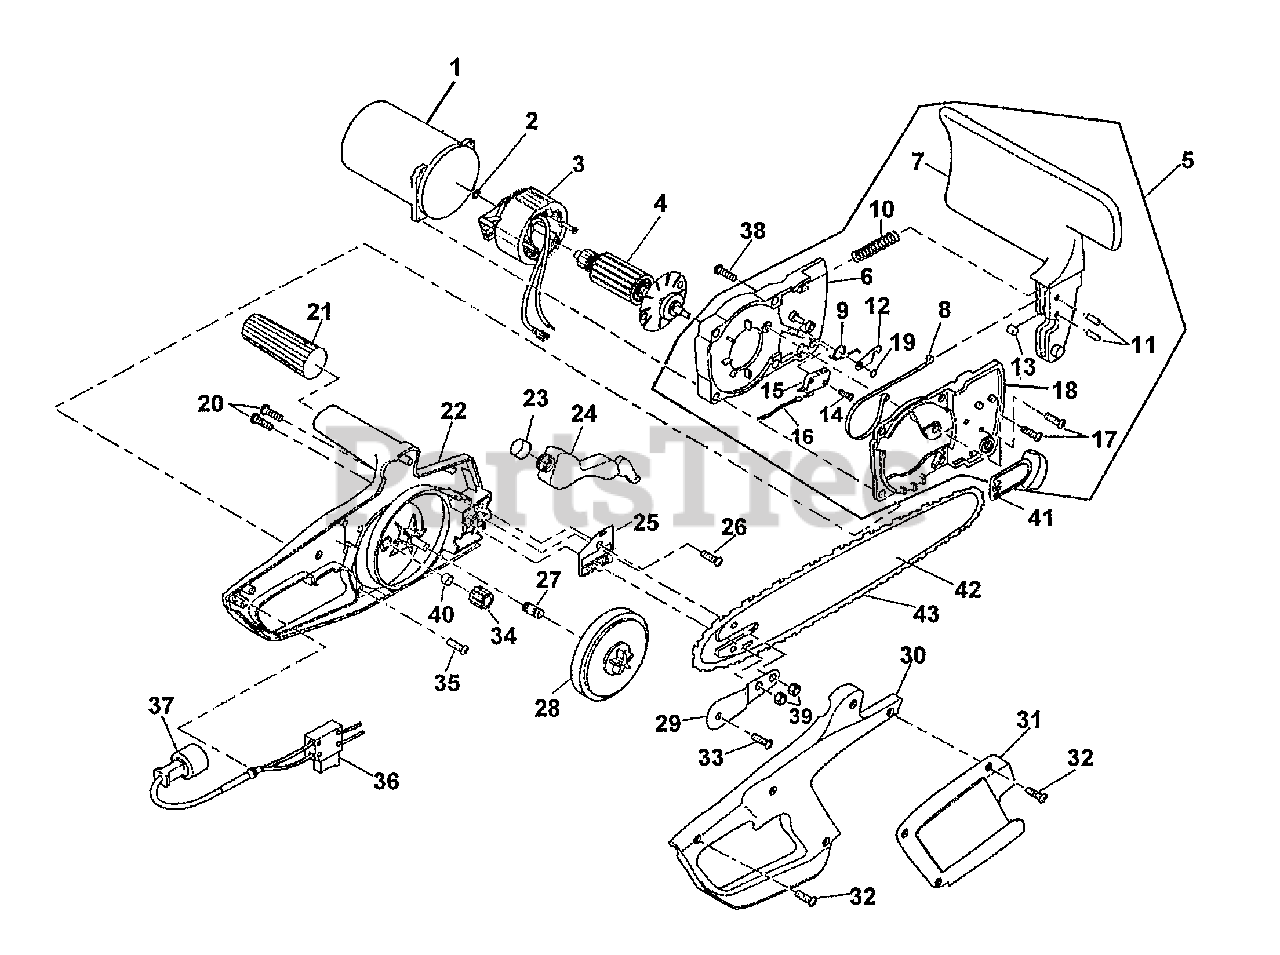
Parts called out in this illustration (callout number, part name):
1	CASE, MOTOR
2	WASHER, THRUST
3	FIELD
4	ARMATURE
5	CHAIN BRAKE ASSY
6	HOUSING, CHAIN BRAKE
7	GUARD, HAND
8	BAND, BRAKE
9	SPRING
10	SPRING
11	PIN - LOCATING
12	LATCH, BRAKE
13	BUSHING
14	SCREW - 4-17 X 5/8"
16	WIRE ASSY
17	SCREW - 10-32 X 7/8"
18	COVER, CHAIN BRAKE
19	RING, RETAINING
20	BOLT - 1/4-20 X 1-3/8
21	GRIP, FOAM
22	GEAR CASE ASSY
23	CAP, OIL
24	TANK, OIL
25	ADJUSTING PLATE ASSY
27	BEARING, SPROCKET
28	GEAR - SPROCKET
29	SUPPORT, SPROCKET
30	COVER, SIDE
31	COVER, SPROCKET
33	SCREW
34	GEAR - DRIVE
35	SCREW - 10-16 X 1-7/8"
36	SWITCH, LOCK OFF
37	CORD
38	SCREW - 6-20 X 1-1/2"
39	LOCKNUT - 1/4-20
40	BEARING, NEEDLE
41	KICK GUARD KIT
42	SAW CHAIN - 12" (30cm)
42	SAW CHAIN - 91VG
43	GUIDE BAR - 12" (30cm)
43	GUIDE BAR - 16" (40cm)
